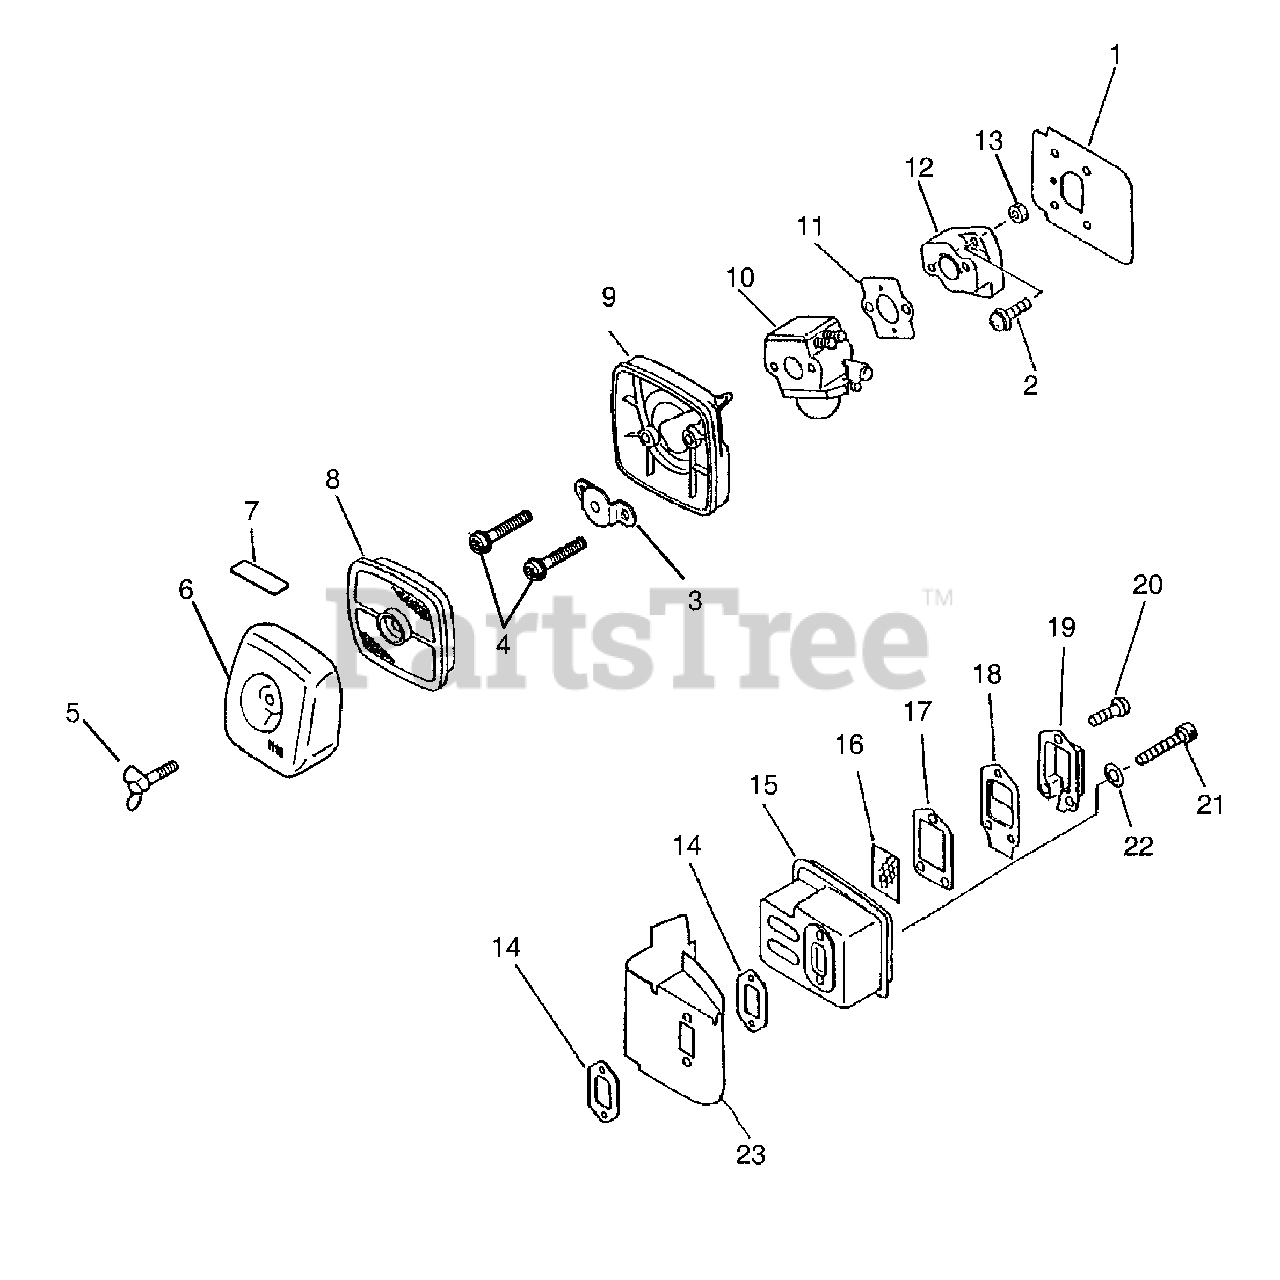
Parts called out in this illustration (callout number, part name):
1	SHIELD, INTAKE
2	SCREW - 5X20
3	PLATE, PREVENT
4	SCREW - 5X65
5	THUMBSCREW
6	COVER, AIR FILTER - GRAY
7	LABEL - CHOKE
8	FILTER, AIR
8	FILTER, AIR - SINGLE LAYER
9	AIR FILTER CASE KIT - GRAY
10	CARBURETOR C1U-K51
11	GASKET, INTAKE
12	INSULATOR, INTAKE
14	GASKET, EXHAUST
16	SCREEN, SPARK ARRESTOR
17	GASKET, EXHAUST
18	GASKET, EXHAUST - INNER
19	GUIDE, EXHAUST - OUTER
20	SCREW - 4X10
21	SCREW - 5X55
22	WASHER - 5
23	SHIELD, EXHAUST
